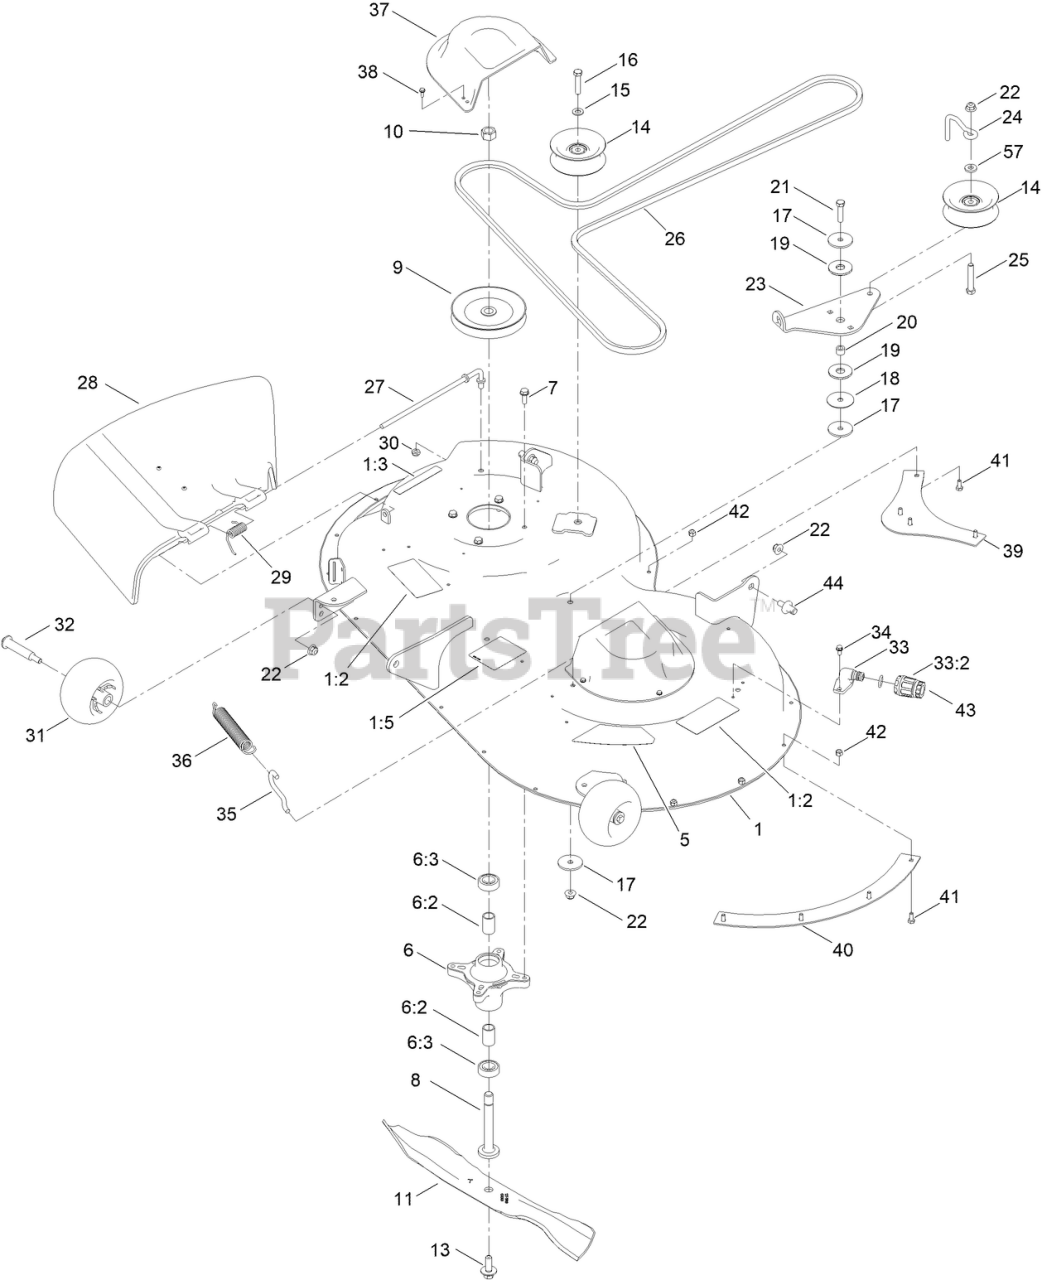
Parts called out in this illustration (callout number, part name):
1	42 INCH DECK AND DECAL ASM
1:2	DECAL-DANGER, DECK
1:3	DECAL-DANGER
1:5	DECAL-ROUTING, BELT
6	SPINDLE ASM
6:2	SPACER
6:3	BEARING-BALL
7	SCREW-TAPTITE
8	SHAFT-SPINDLE
9	Pulley
10	NUT-HEX
11	BLADE-21.6 IN
13	BOLT-BLADE, SEMS
14	PULLEY-IDLER, FLAT
15	WASHER-FLAT
16	SCREW-HH
17	WASHER-REBOUND
18	WASHER
19	WASHER-FRICTION, COMPOSITE
20	SPACER
21	SCREW-HH
22	NUT-HF, NI
23	ARM-IDLER
24	BELT GUIDE - IDLER
25	SCREW-HH
26	V-BELT
27	ROD-PIVOT
28	DEFLECTOR
29	SPRING-TORSION
31	ROLLER-SCALP, ANTI
32	BOLT-SHOULDER
33	FITTING-WASHOUT
33:2	O-RING
34	SCREW-HWH
35	HOOK-RETURN SPRING
36	SPRING-EXTENSION
37	COVER-BELT
38	SCREW-TAPTITE
39	BAFFLE-BLOWOUT, REAR
40	BAFFLE-BLOWOUT, SIDE
41	SCREW-HH
42	NUT-LOCK, NI
43	CONNECTOR-HOSE
44	PIN-DECK
57	SPACER-HUB, BLOWER
